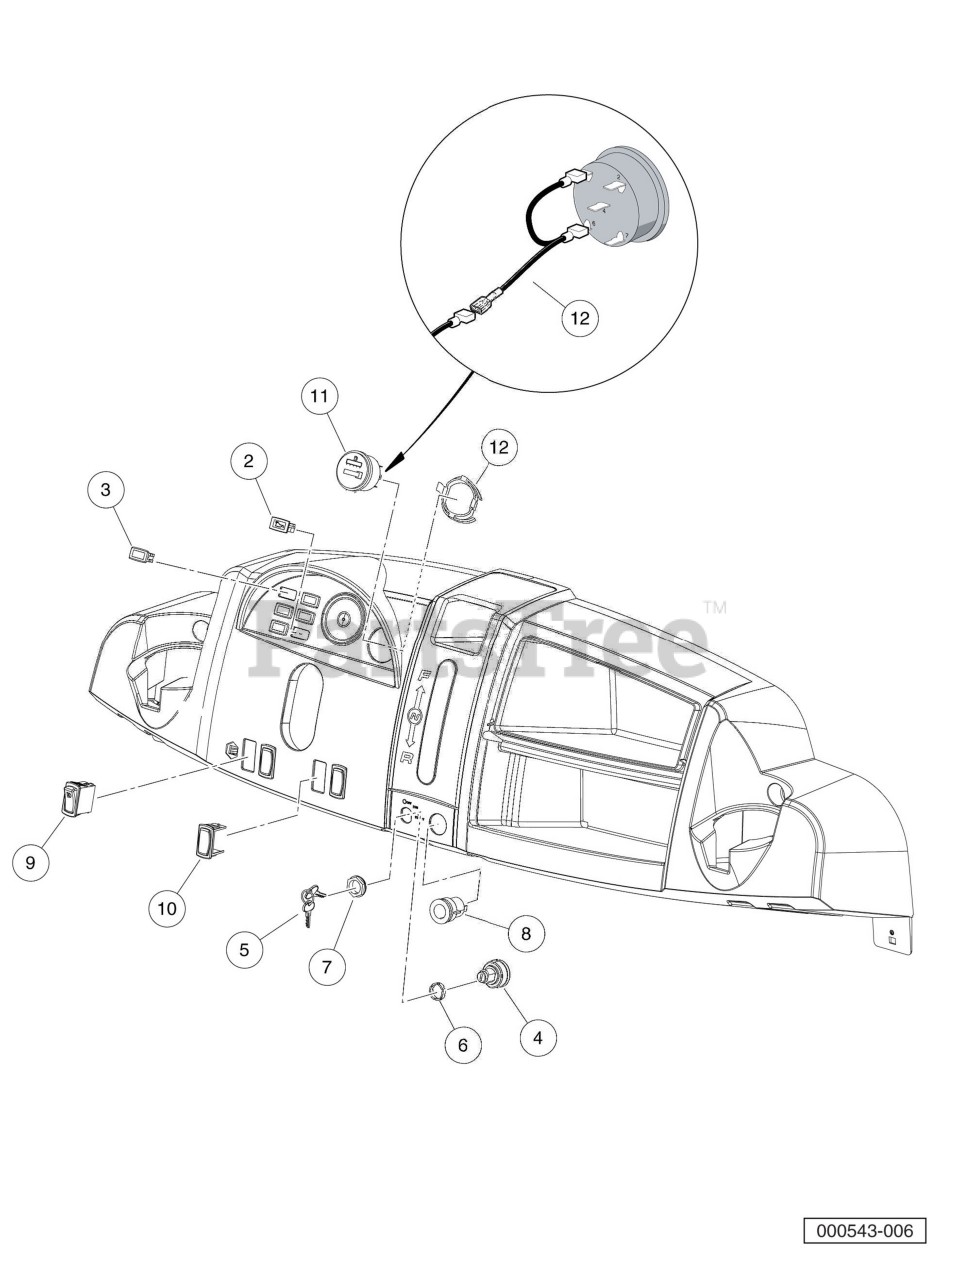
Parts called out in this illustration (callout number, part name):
2	Light, Oil
3	Plug, Hole.
4	Key Switch 12v Key Start
6	Spacer, Keyswitch.
7	Nut, Key Switch
8	Receptacle, Accessory
9	Switch, Rocker, Light
10	Cover, Hole, Switch, Rocker
11	Gauge Fuel-hour Sep Gnd
12	Clip, Meter, Round
13	Asm Wire Meter F-h Jumper
